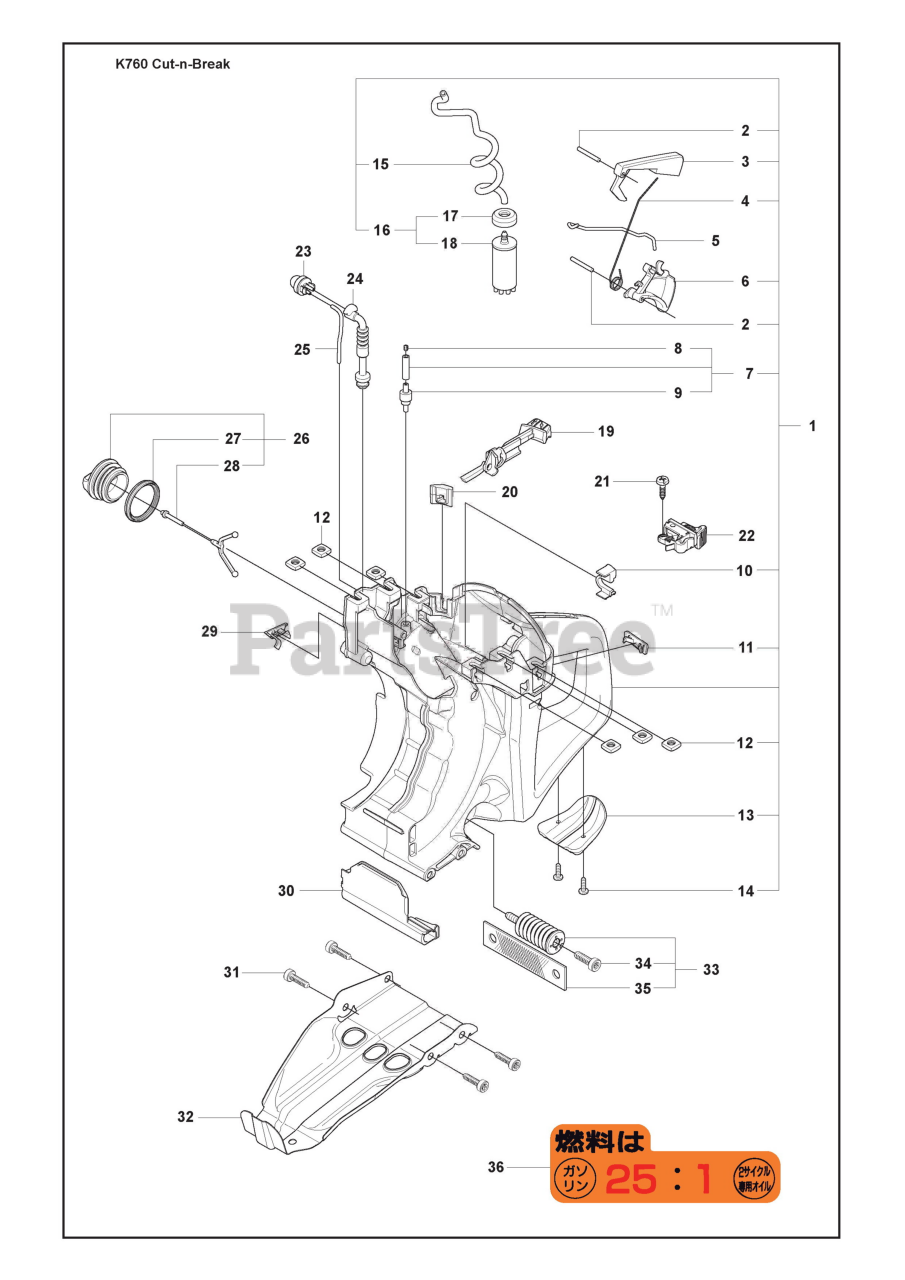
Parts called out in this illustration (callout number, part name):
1	Fuel Tank
2	Parallel Pin
3	Throttle Lockout
4	Spring
5	Throttle Rod
6	Throttle Trigger
7	Tank Vent Assy
8	Sinter Plug
13	Ground Support
15	Fuel Hose
16	Fuel Filter
17	Hose Clamp
18	Fuel Filter
19	Choke Control
22	Stop Switch
23	Primer Housing
24	Fuel Hose
25	Fuel Hose
26	Tank Cap Assy
28	Tank Cap Holder
30	Heat Shield
32	Base Plate
33	Vibration Absorber
